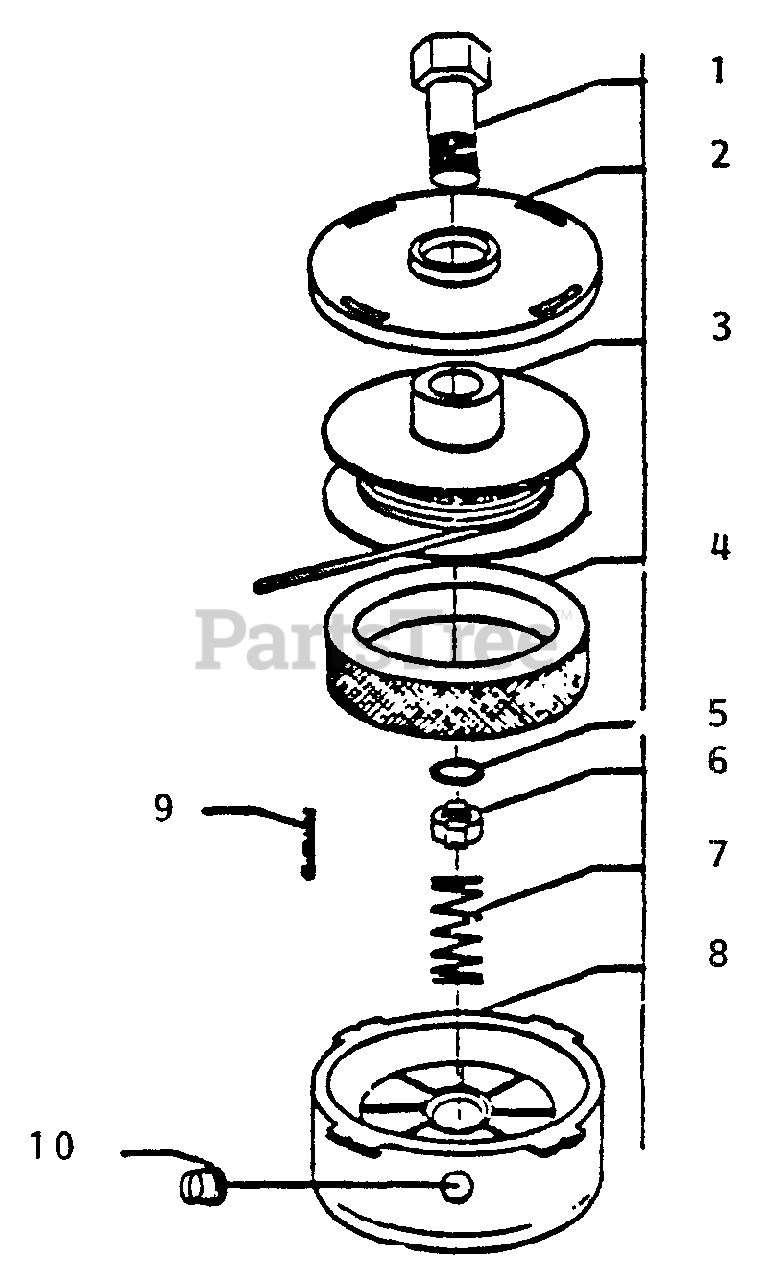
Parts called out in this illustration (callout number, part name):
1	ADAPTOR, DRIVE
2	PLATE - REAR
3	SPOOL ASSY
4	PAD, FOAM
5	O-RING
6	NUT
7	SPRING
8	HUB
9	PIN - COTTER
10	EYELET
